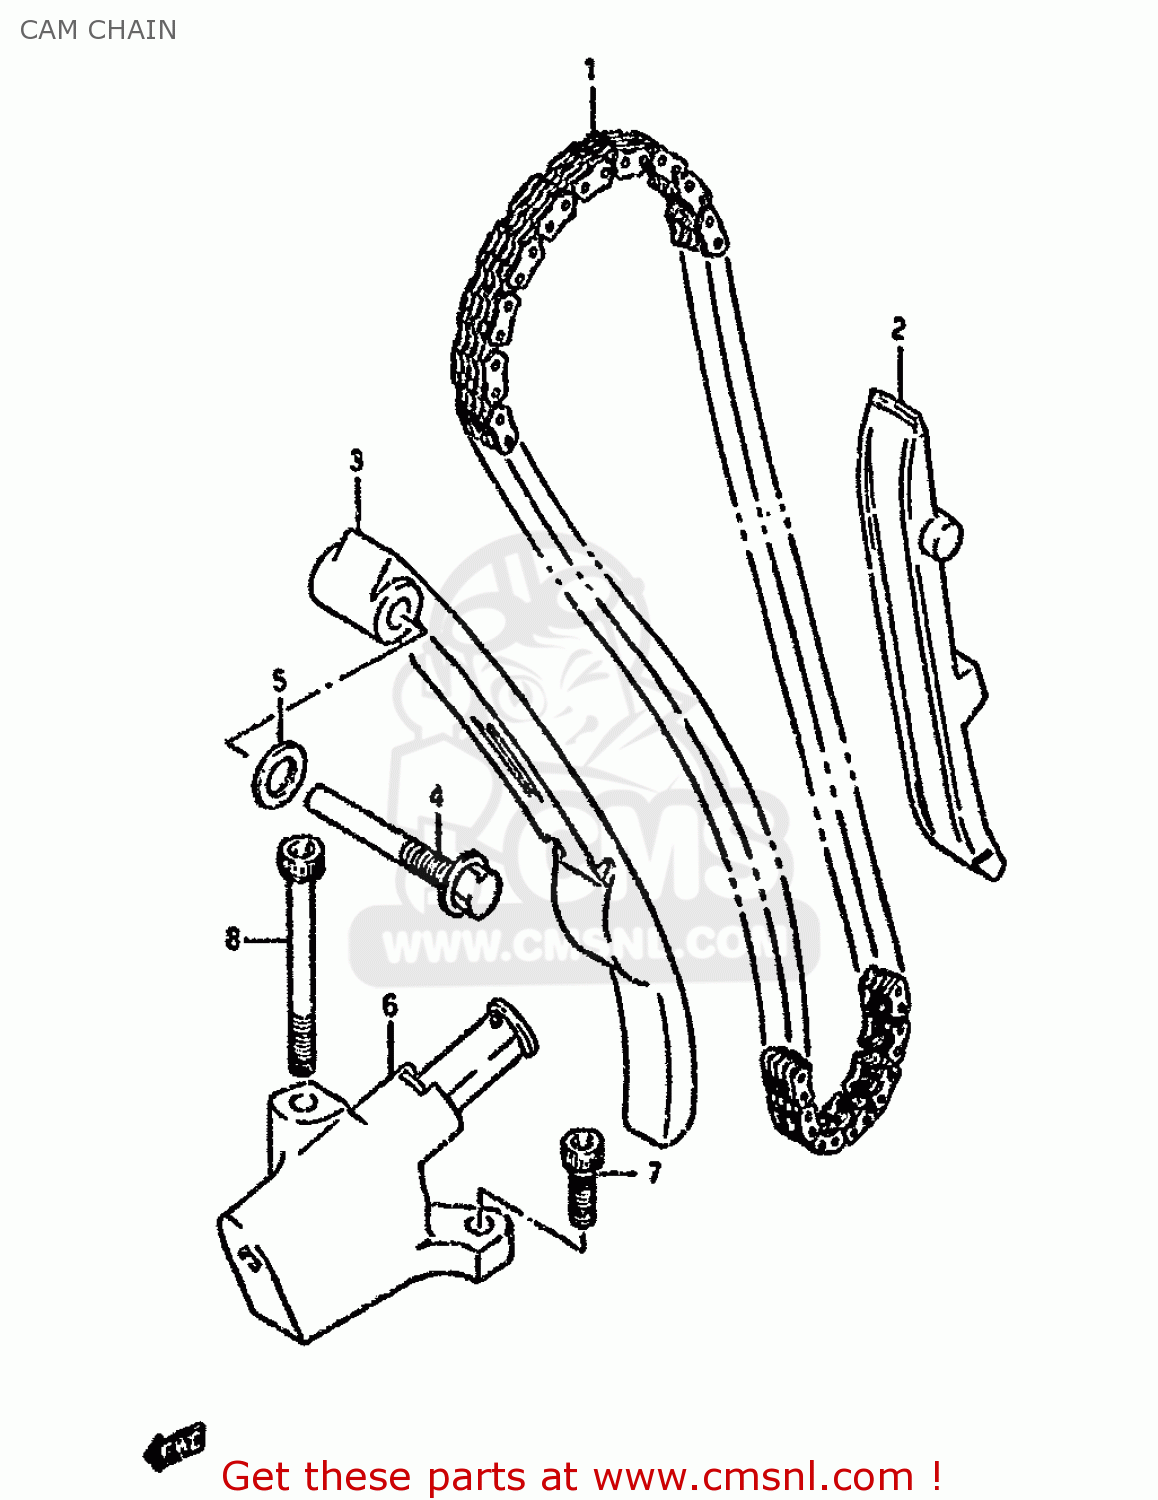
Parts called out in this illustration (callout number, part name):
1	CHAIN,CAMSHAFT DRIVE
2	GUIDE,CAM CHAIN
3	TENSIONER,CAM CHAIN
4	BOLT,CAM CHAIN TENSIONER
5	GASKET 8.2X14X1 (NAS)
6	ADJUSTER ASSY,TENSIONER
7	BOLT
8	BOLT
